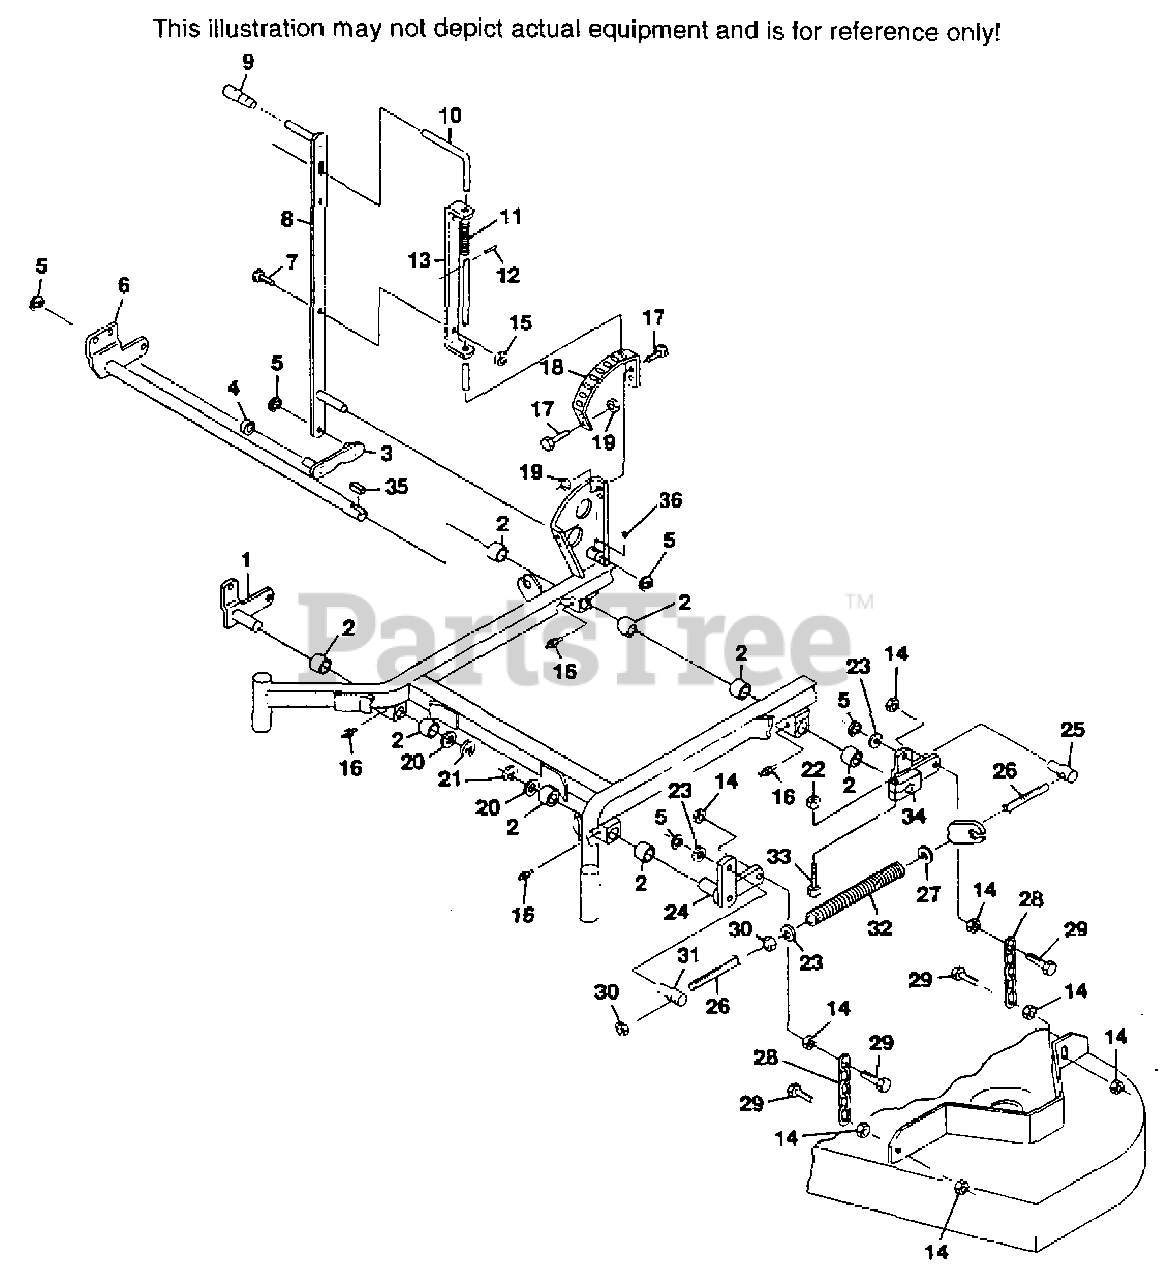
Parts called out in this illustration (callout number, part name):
1	BELLCRANK, LIFT - RIGHT FRONT
2	BUSHING
3	LIFT LINK
4	BUSHING
5	RETAINING RING, 5/8" EXTERNAL "E"
6	LIFT ARM WELDMENT
7	CAPSCREW, 5/16-18 X 1" SERRATED FLANGE HEX
8	HEIGHT ADJUSTMENT LEVER(INCLUDES GRIP)
9	GRIP, LIFT LEVER
10	ROD, CUTTER DECK LOCK
11	SPRING, DECK LIFT INDEX
12	ROLL PIN, 5/32 X 3/4"
13	LOCK ROD GUIDE
14	NUT 3/8-16 SERRATED FLANGE
15	NUT, 5/16-18 SERRATED FLANGE
16	GREASE FITTING
17	CAPSCREW, 1/4-20 X 3/4" SERRATED FLANGE HEX
18	STRIP, HEIGHT ADJUSTMENT
19	NUT, 1/4-20 SERRATED FLANGE
20	FLAT WASHER, 3/4" SPECIAL
21	RETAINING RING, 3/4" EXTERNAL "E"
23	FLAT WASHER, 5/8" SPECIAL
24	BELLCRANK, LIFT - LEFT FRONT
25	SWIVEL JOINT - LH
26	ADJUSTMENT STUD
27	FLAT WASHER, 5/8" ID
28	CHAIN
31	SWIVEL JOINT - RH
32	SPRING, DECK LIFT
34	BELLCRANK, LIFT - LEFT REAR
35	KEY, 3/16 X 3/16 X 1"
36	GREASE FITTING
